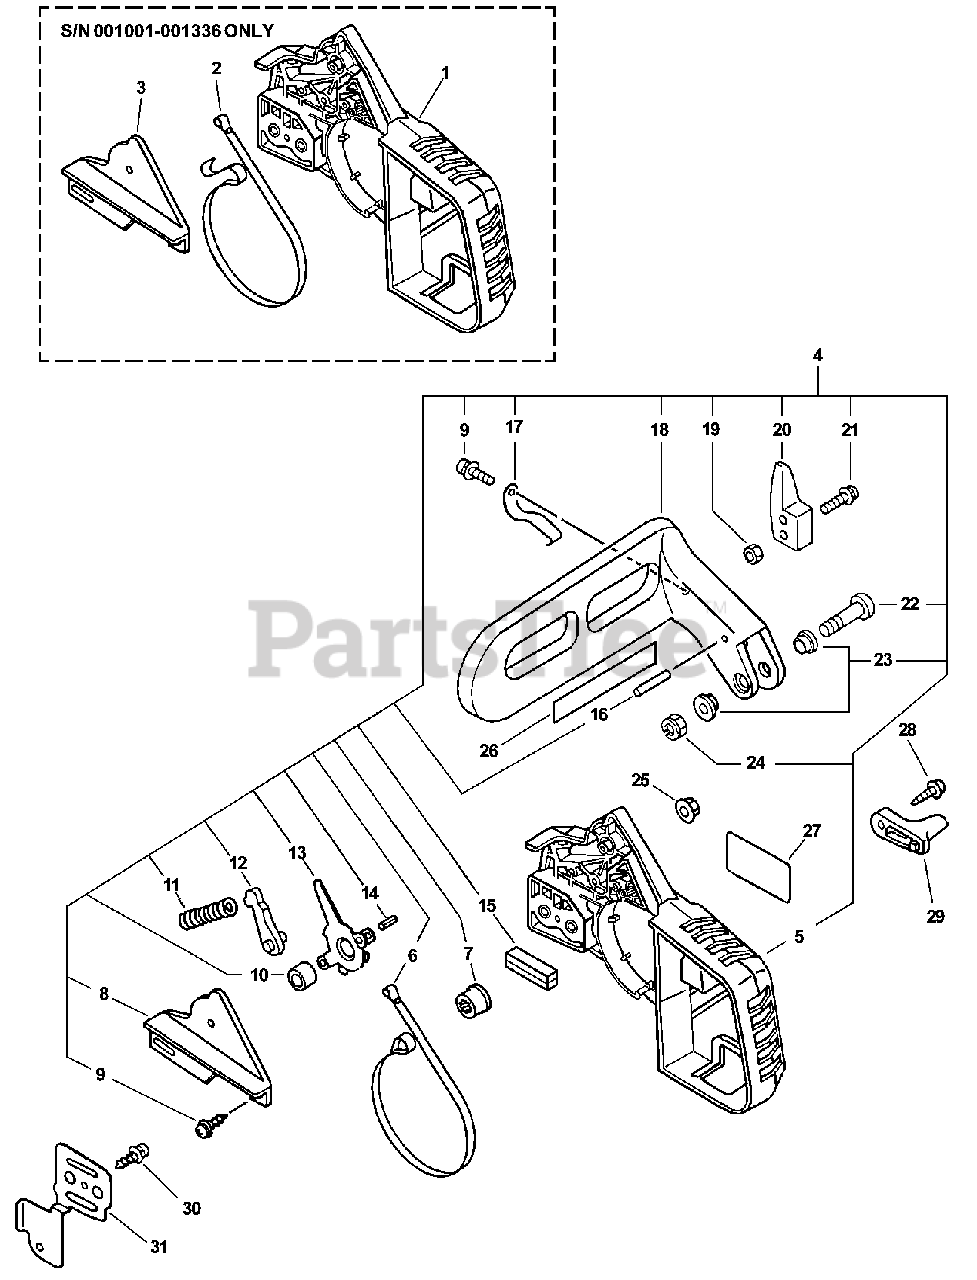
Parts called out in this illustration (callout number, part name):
1	GUARD, SPROCKET
2	BAND, BRAKE
3	COVER, BRAKE
4	CHAIN BRAKE ASSY
5	GUARD, SPROCKET
6	BAND, BRAKE
7	ADJUSTER, BRAKE BAND
8	COVER, BRAKE - GRAY
9	SCREW - 4X10
10	SPACER - 8
11	SPRING, BRAKE
12	STOPPER, BRAKE
13	LEVER, BRAKE
14	PIN - SPRING -- 4X8
16	ROLLER - 4X23.8
17	SPRING, RETURN
18	LEVER, BRAKE
20	WEIGHT, BRAKE
21	SCREW - 4X20
22	SCREW - 5X30
24	LOCKNUT - 5
25	NUT - 6 -- FLANGE
26	LABEL - BAR & CHAIN -- US
26	LABEL - BAR & CHAIN -- CANADA
27	LABEL - MODEL
28	SCREW - 5X20 -- TAPPING
29	CATCHER, CHAIN
30	SCREW - 4X10
31	PLATE, GUIDE - OUTER
